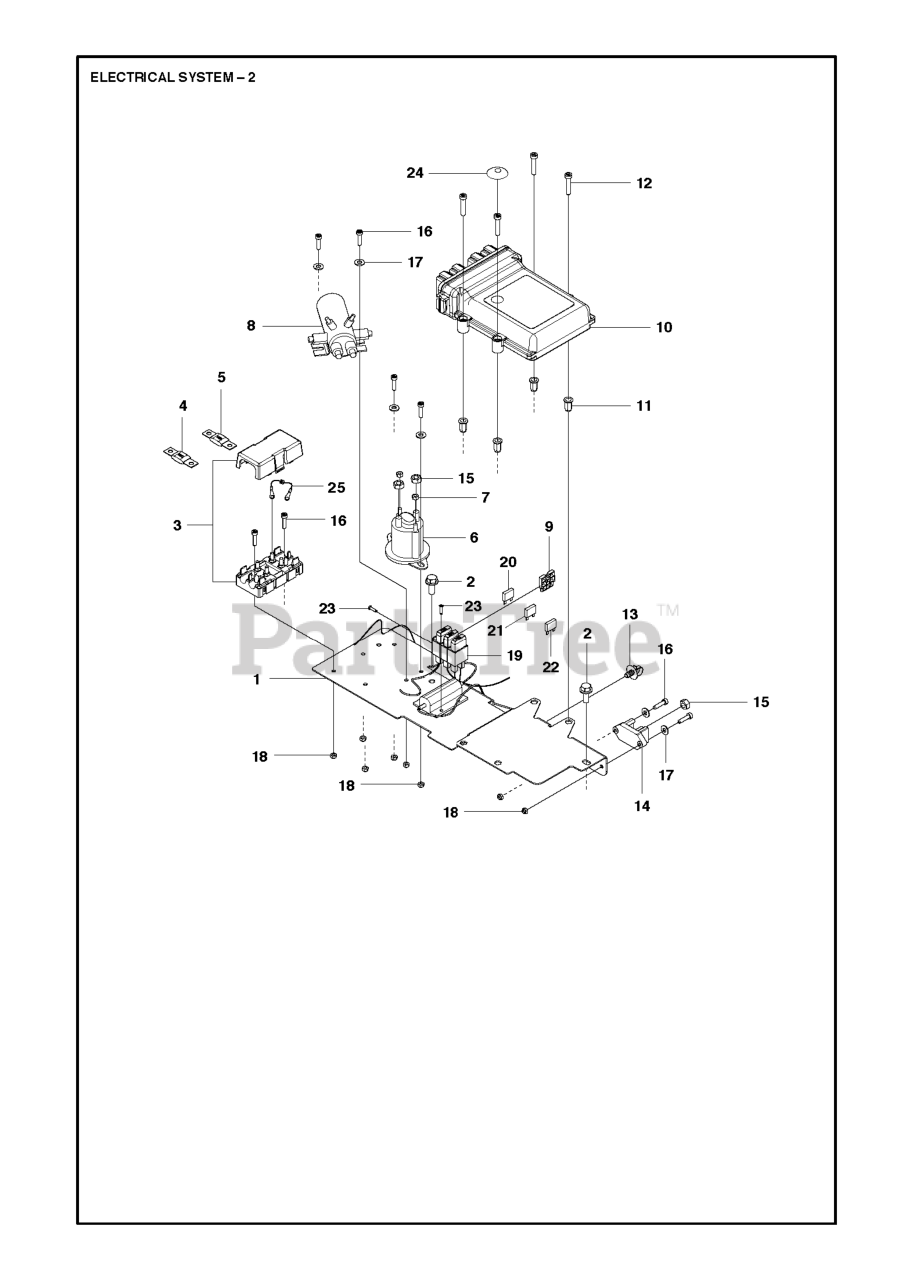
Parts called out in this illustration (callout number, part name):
12	SCREW ITXSCM M6X30 T27 10.9 Z
15	NUT
16	SCREW ITSXCM
17	WASHER
18	LOCKNUT M5
